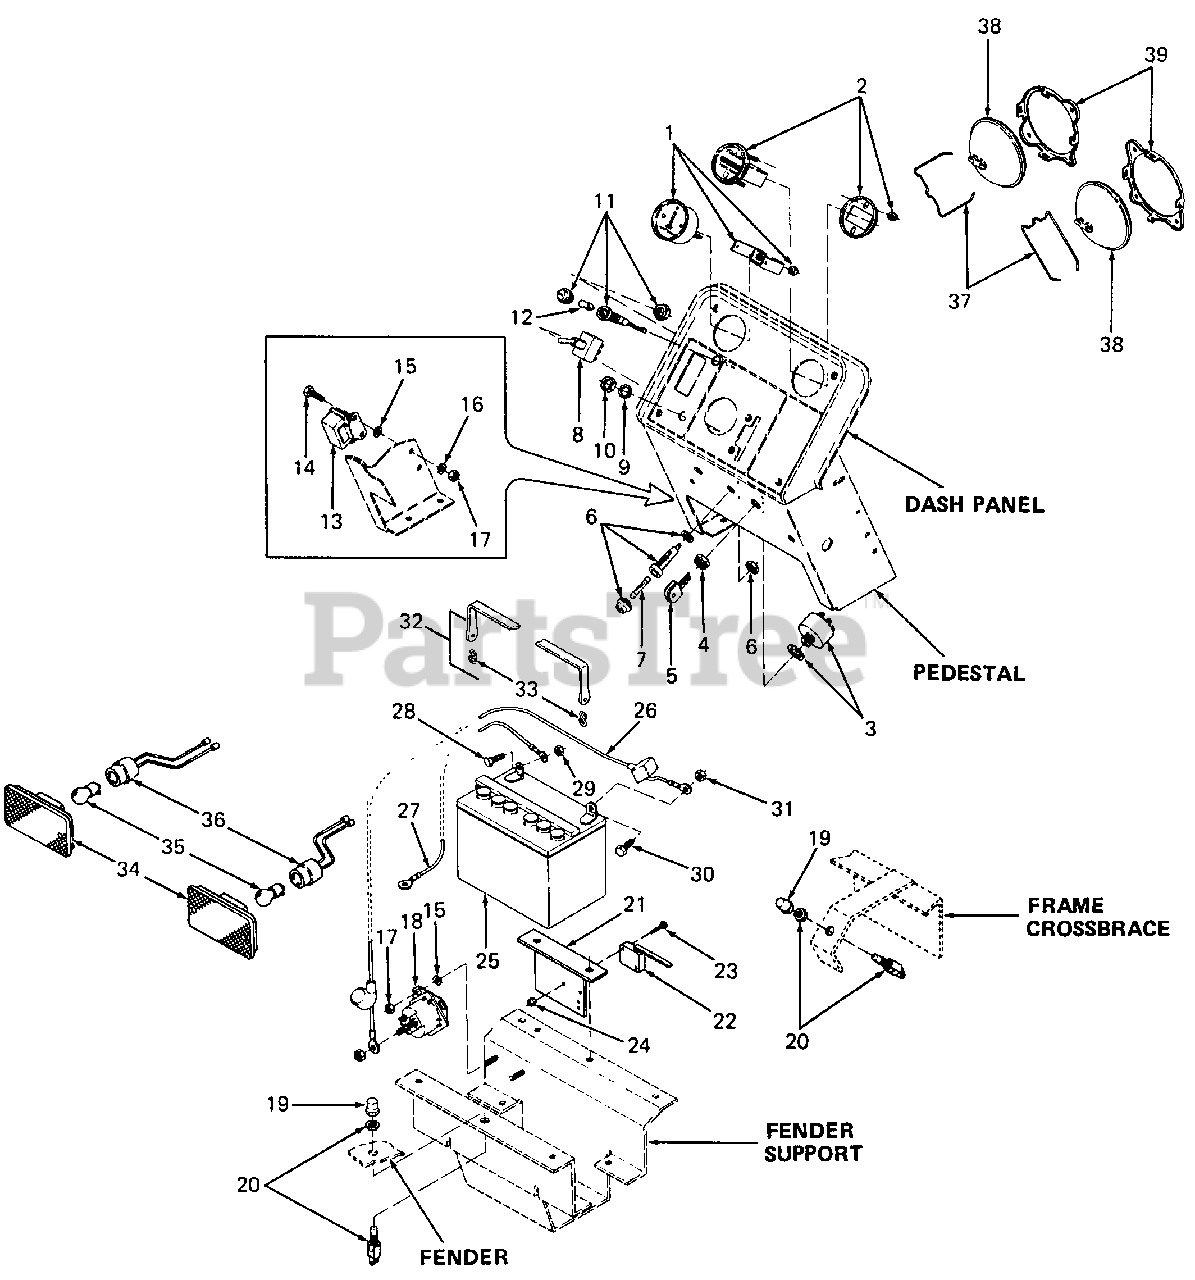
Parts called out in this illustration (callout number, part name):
1	Ammeter
2	Hourmeter
3	Switch, Ignition Key
4	Nut, Switch
5	Key, Ignition (Set of 2)
6	Fuse Holder
7	Fuse, 20 Amp
8	Switch, PTO
9	Washer, Flat, .531 X .680 X .054 Thk
10	Nut, Hex, 1/2-27 X .100 Thk
11	Light Assy, Oil Indicator
12	Bulb, Light
13	Relay
14	Screw, Hex Cap, 1/4-20 X .62 Lg GR5
15	Washer, Ext Lock, 1/4
16	Washer, Lock, 1/4
17	Nut, Hex, 1/4-20 GR5
18	Solenoid
19	Boot, Switch
20	Switch w/Nut
21	Bracket, Micro Switch
22	Switch, Reverse
23	Screw, Hex Mach, #4-40 X .75 Lg
24	Nut, Hex Insert Lock, #4-40
25	Battery
26	Cable, Positive Battery
27	Cable, Negative Battery
28	Bolt, Carriage, 1/4-20 X .75 Lg
29	Nut, Hex, 1/4-20 GR5
30	Bolt, Carriage, 5/16-18 X .75 Lg
31	Nut, Hex, 5/16-18 GR5
32	Strap Assy, Battery
33	Hook, Battery Strap
34	Lens Assy, Tail Light
35	Bulb, Light
36	Cable Assy, Tail Light
37	Spring, Headlight Retaining
38	Headlight
39	Retainer, Headlight
